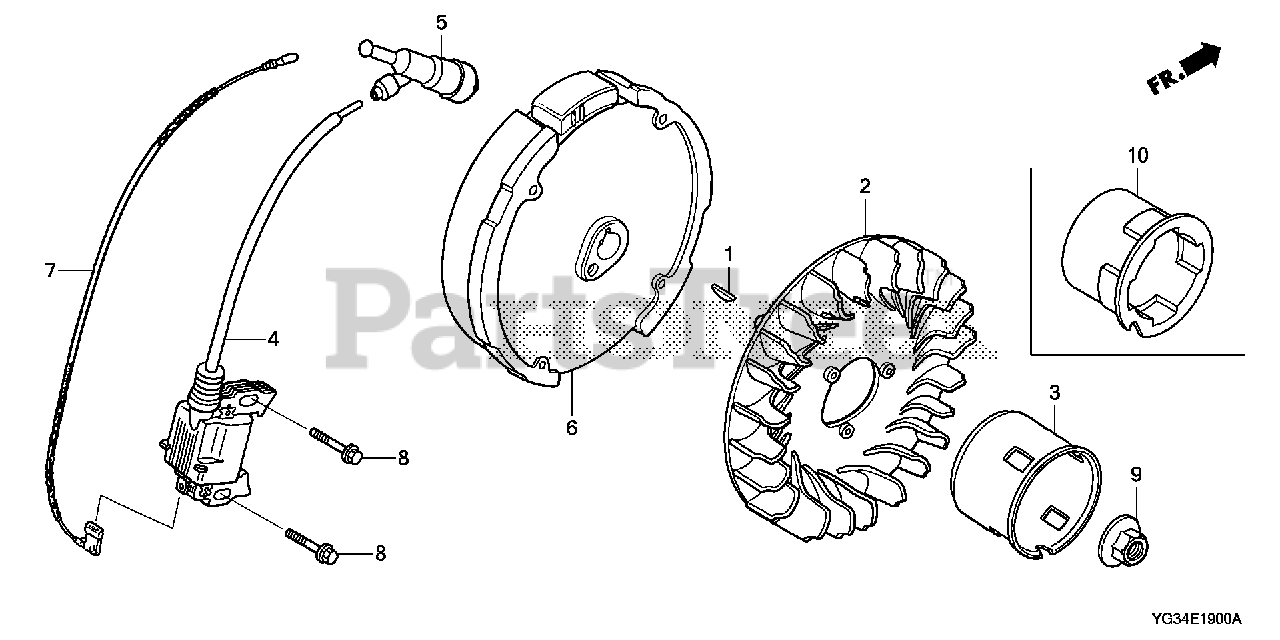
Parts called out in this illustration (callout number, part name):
1	KEY, SPECIAL WOODRUFF (25X18)
2	FAN, COOLING
4	COIL ASSY., IGNITION (TEC)
5	CAP ASSY., NOISE SUPPRESSOR (TEC)
6	FLYWHEEL (YUXIN)
7	WIRE, STOP SWITCH (370MM)
8	BOLT, FLANGE (6X25) Use up to Engine SN 2056819.
9	NUT, SPECIAL (14MM)
10	PULLEY, STARTER
